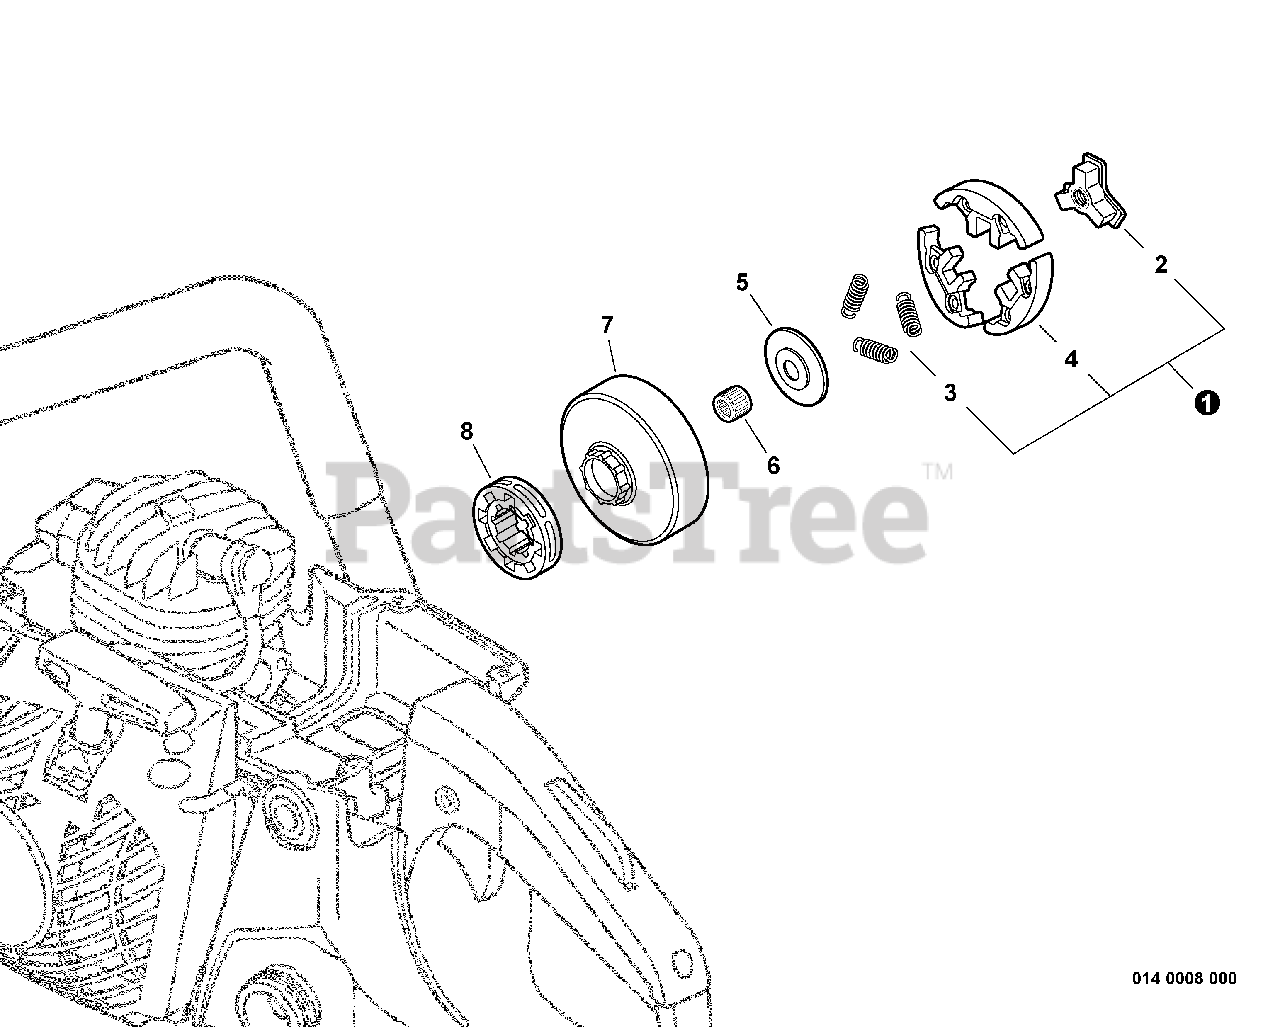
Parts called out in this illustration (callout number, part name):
1	CLUTCH ASSY
2	HUB, CLUTCH
3	SPRING, CLUTCH
4	CLUTCH SHOE SET
5	PLATE, CLUTCH
6	BEARING, NEEDLE
7	DRUM, CLUTCH
8	SPROCKET, RIM
